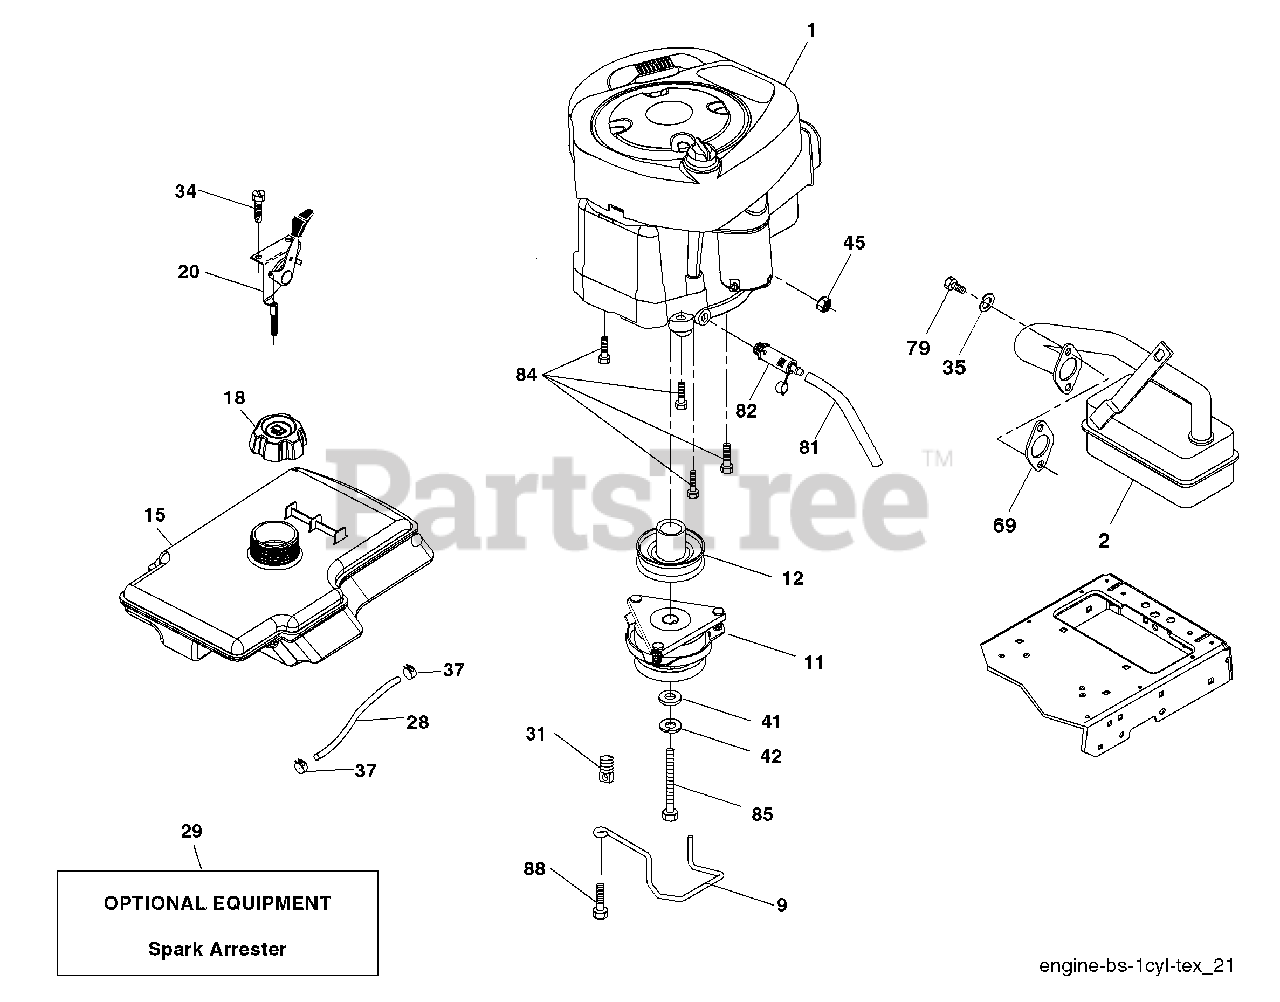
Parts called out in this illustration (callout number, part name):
9	Keeper Belt Engine
11	Clutch Ogura
12	Pulley Engine
15	Tank Fuel
18	Cap Asm
20	Control Throttle
28	Fuel Line
29	Spark Arrester Kit
31	Clip Push-In Hinged
34	Screw thd Cut 1/4-20 x 1/2
35	Washer Split
37	Clamp Hose
41	Washer 1-1/2 OD x 15/32 ID x .250
42	Washer Lock 7/16
45	Nut Keps Hex 1/4-20 unc
69	Gasket
79	Screw Socket Head 5/16-18 x .75
81	Tube Drain Oil Easy
82	Plug Drain Oil
84	Screw 3/8-16 x 1-1/4
85	Bolt Hex 7/16-20 x 4 x Gr. 5-1.5 Thr
88	Screw 3/8-16 x 1
